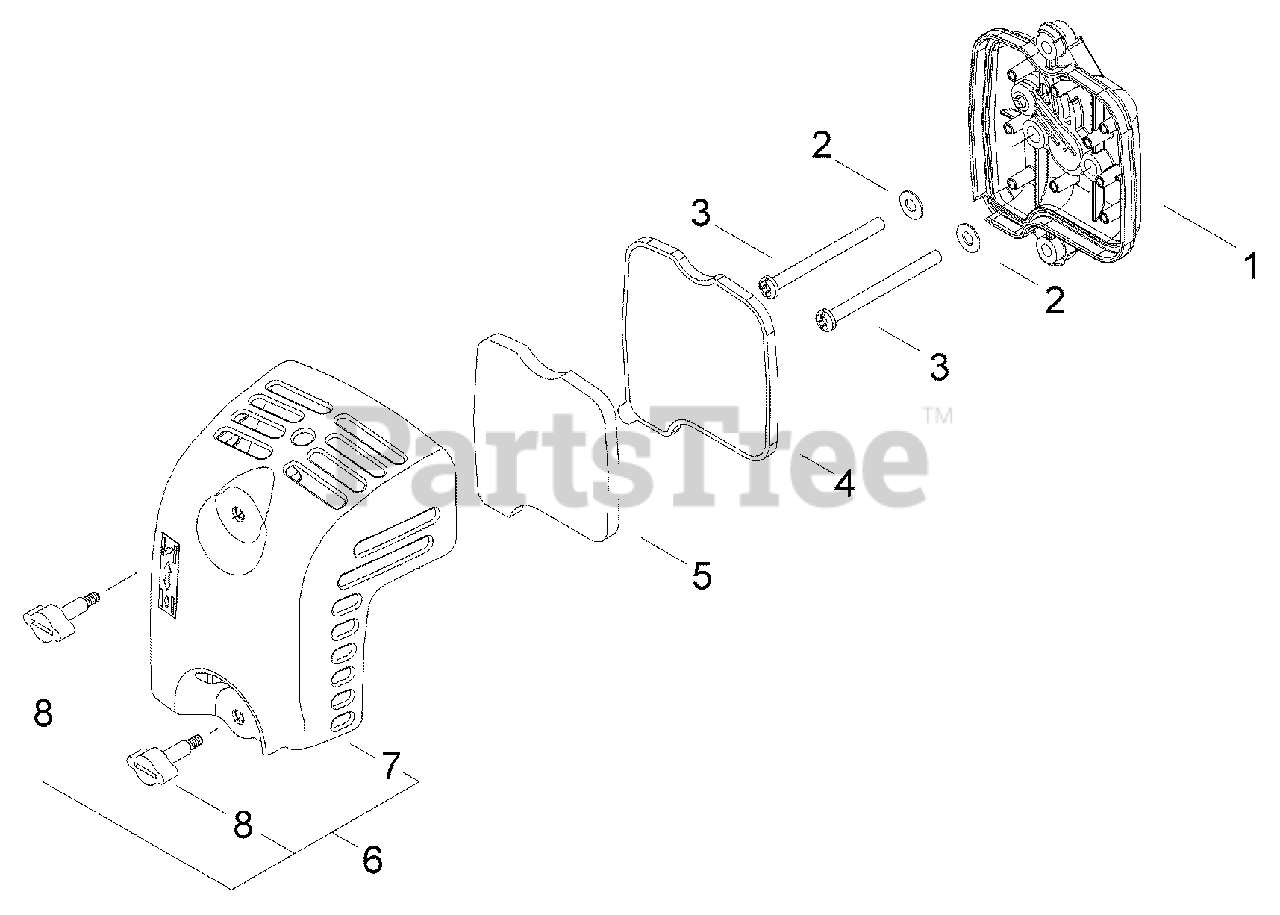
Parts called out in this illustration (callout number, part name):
1	CASE ASSY, AIR FILTER
2	WASHER 5 MM
3	SCREW M5×60
4	FILTER, AIR
5	PRE-FILTER, FOAM
6	COVER ASSY, AIR FILTER
7	COVER, AIR FILTER
8	THUMBSCREW M5
